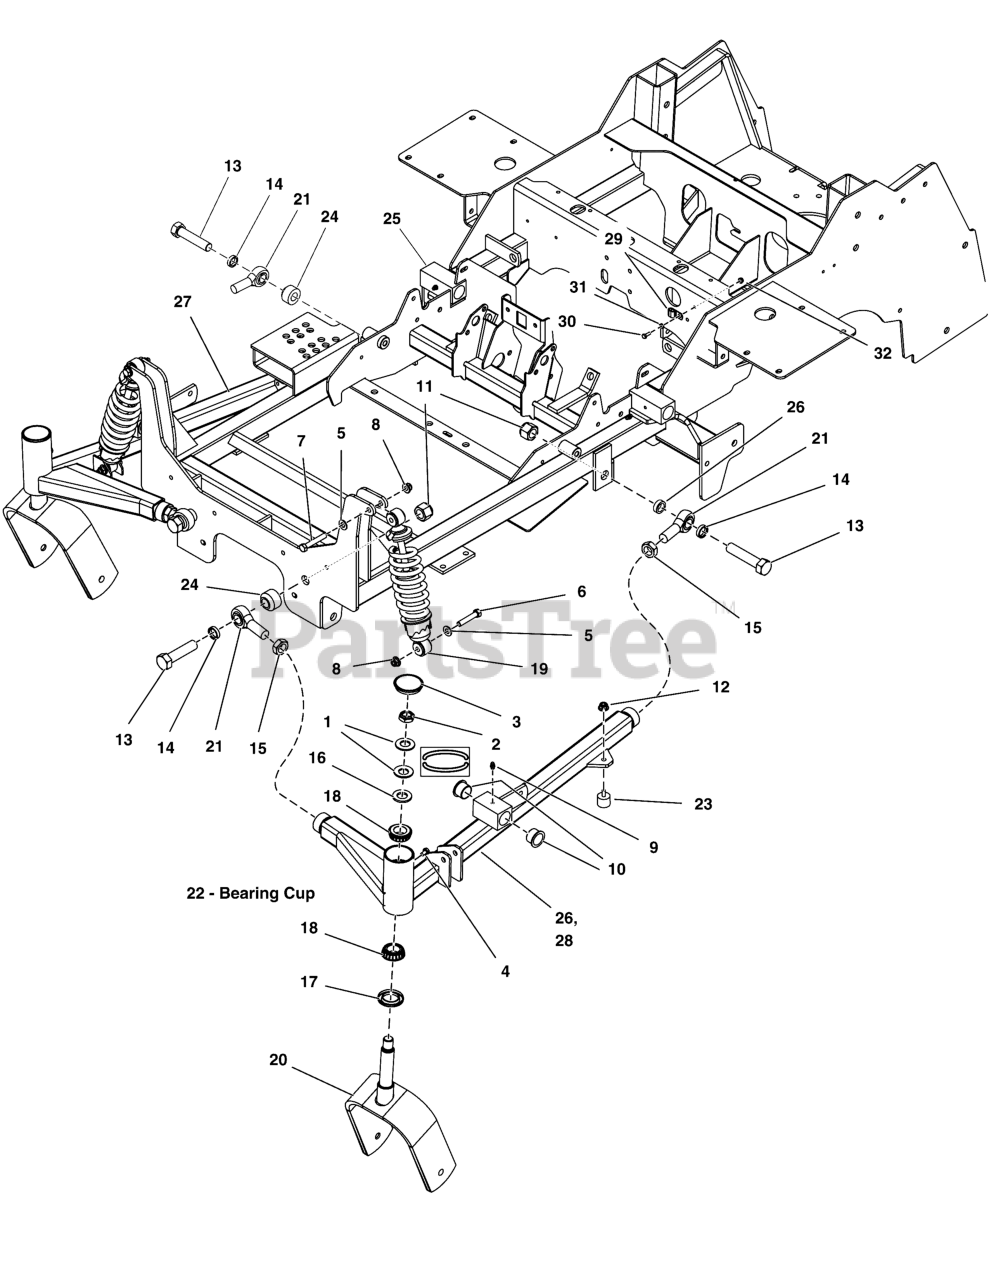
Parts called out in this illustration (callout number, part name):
1	WASHER, BELLEVILLE - 1.500 X .755
2	NUT, 3/4-16, HEX JAM NYLON LOCK
3	CAP, GREASE, LOW PROFILE
4	BOLT, 1/4-28 X 1/2, GD5 YZ
5	WASHER, 3/8 SAE
6	BOLT, 3/8-16 X 2, GD5, CZ
7	BOLT, 3/8-16 X 2-1/4" GD5 CZ
8	NUT, 3/8 - 16 HEX NYLOCK FLANGE
9	GREASE FITTING, 1/4-28 Straight
10	BUSHING, 1.00 X 1.13 X 1.38, Plastic
11	NUT, Hex, Nylon Lock, 3/4-16
12	NUT, 1/4-20 HEX SERR. FLANGE
13	BOLT, 3/4-16 X 3-1/2" YZ GD5
14	SPACER, .76 x 1.00 x .25
15	NUT, Hex, Jam, 3/4-16
16	WASHER, 3/4 SAE
17	SEAL, GREASE
18	BEARING, TAPERED ROLLER, 1"
19	SHOCK / SPRING ASSEMBLY, OE22375
20	WELD, CASTER YOKE - RED
21	BALL JOINT, 3/4-16, MALE
22	CUP, BEARING (SV)
23	BUMPER, RUBBER, 1/4-20
24	SPACER, .75 X 1.50 X 1.00, CZ
25	FRAME
26	SPACER, .765 X 1.13 X .375, CZ
27	WELD, A-ARM, IS3200Z, RH - RED
28	WELD, A-ARM, 72, LH - RED
29	CLAMP, 5/16", DOUBLE, WIRE & TUBE
30	BOLT, 1/4"-20 X 3/4" GD5 YZ
31	WASHER, 1/4 SAE
32	NUT, 1/4-20 Hex Nylock Flange
